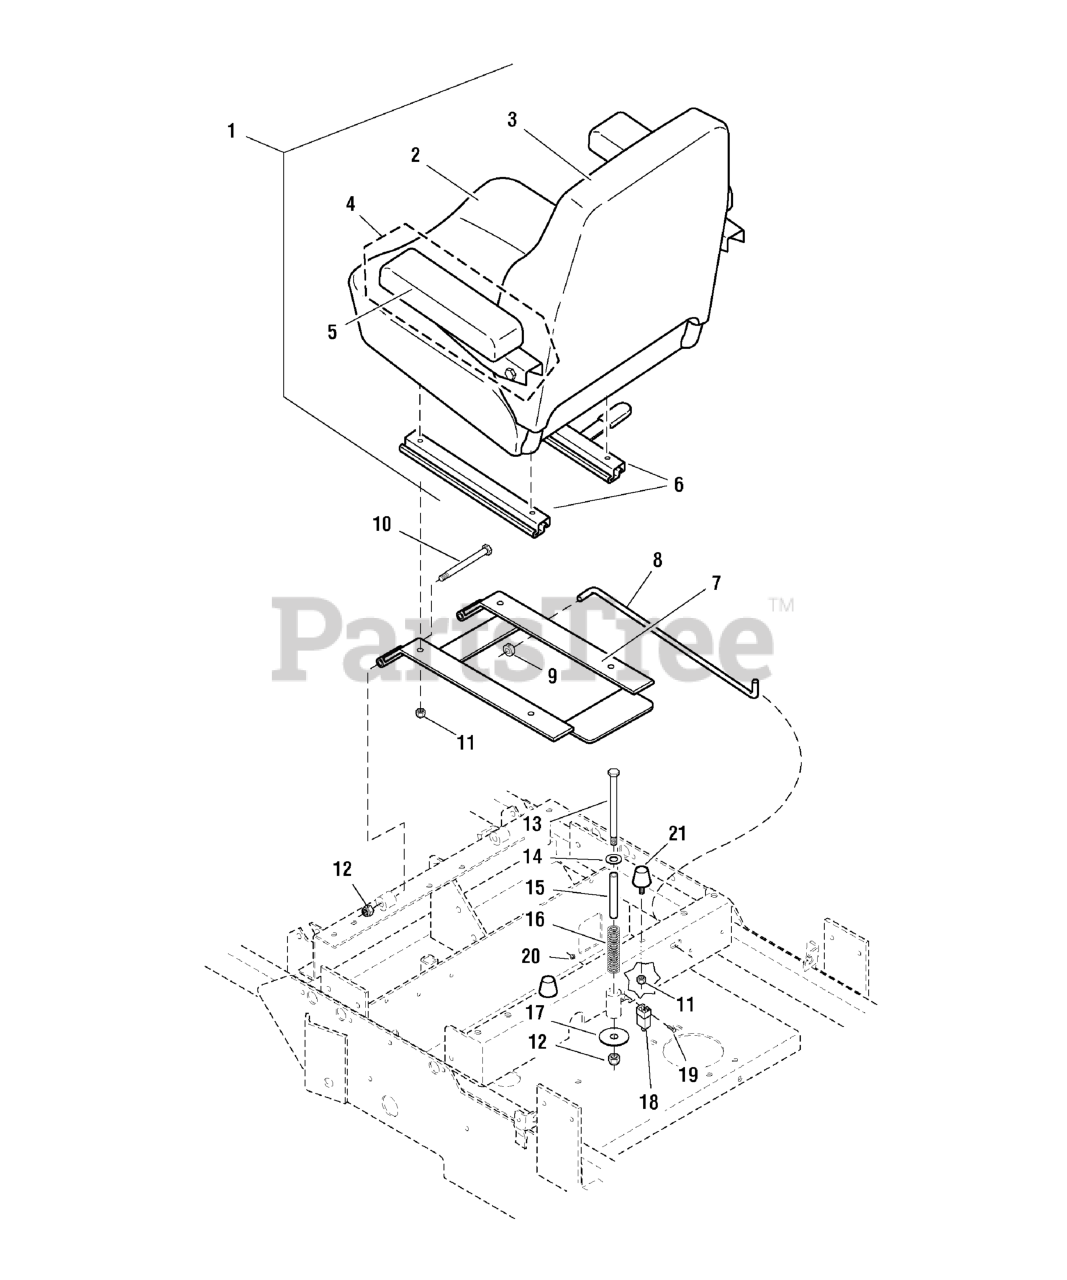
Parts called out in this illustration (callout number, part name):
1	SEAT, Deluxe, Gray, Complete
2	SEAT Bottom Cover
3	SEAT Back Cover
4	ARM REST SET
5	ARM REST PADS
6	SEAT ADJUSTER RAILS (set of 2)
7	WELD, SEAT MOUNT
8	SEAT STOP ROD
9	COLLAR, 5/16" Set
10	BOLT, 3/8-16 X 4" GD5 CZ
11	NUT, 5/16-18 Hex Nylon Lock
12	NUT, 3/8-16 HEX NYLON LOCK
13	BOLT, 3/8-16 X 6" GD5 CZ
14	WASHER, 3/8 SAE
15	SPACER, .38 X .50 X 5.06
16	SPRING, Compression
17	WASHER, 3/8 x 2
18	SWITCH, Plunger, NO/NC
19	SCREW, #10-24 X 1 RS, CZ
20	NUT, #10-24 Hex
21	RUBBER BUMPER
22	SPRING, EXTENSION, SEAT ADJUSTMENT (YEL OR BLK)
